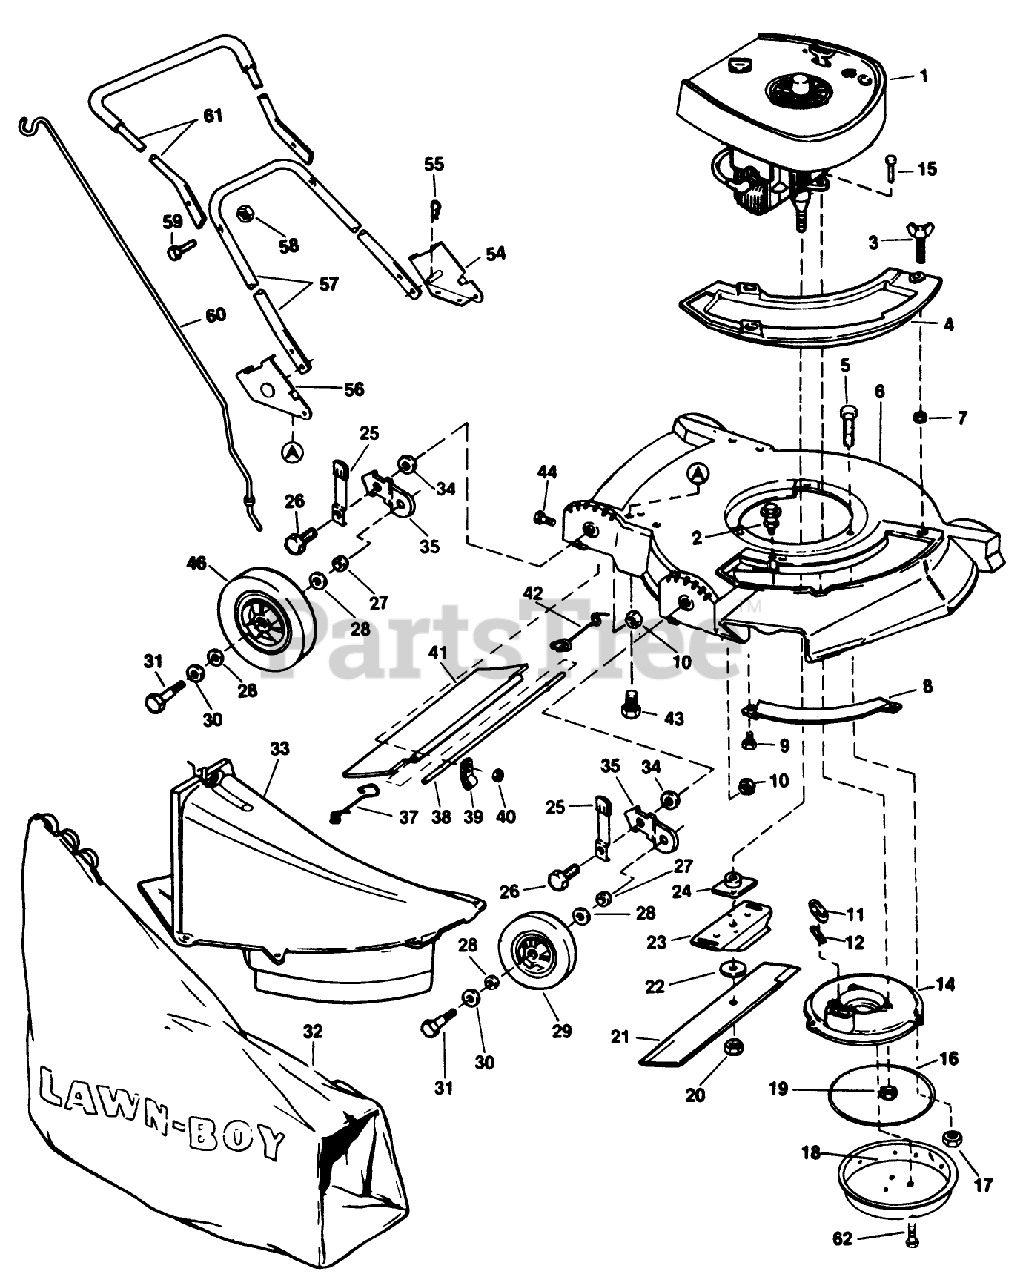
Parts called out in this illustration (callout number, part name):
1	See Page 32 for Engine, Magneto and Carburetor Parts List. See Note #2 at bottom of this page.
3	WING SCREW LAWRE
5	SCREW V
8	TOE BAR 19"
8	BAR-TOE
10	LOCKNUT
12	GASKET S
16	GASKET S
17	NUT-LOCK F
19	NUT-LOCK F
20	NUT-BLADE
22	WASHER
24	PLATE AND COLLAR ASM
27	WASHER WROUGHT
29	WHEEL & TIRE KIT
31	BOLT WHEEL
32	89802 LB WHOLE GOODS
37	SPRING;TRAILING SHIELD RH
38	ROD T/SHIELD ADV WIRE
38	ROD 21" ADVANCE
39	CLAMP ROD KMC
40	LOCKNUT E
42	SPRIG T/SHLD ASOC
55	HAIR PIN
60	ROD GRASSBAG
